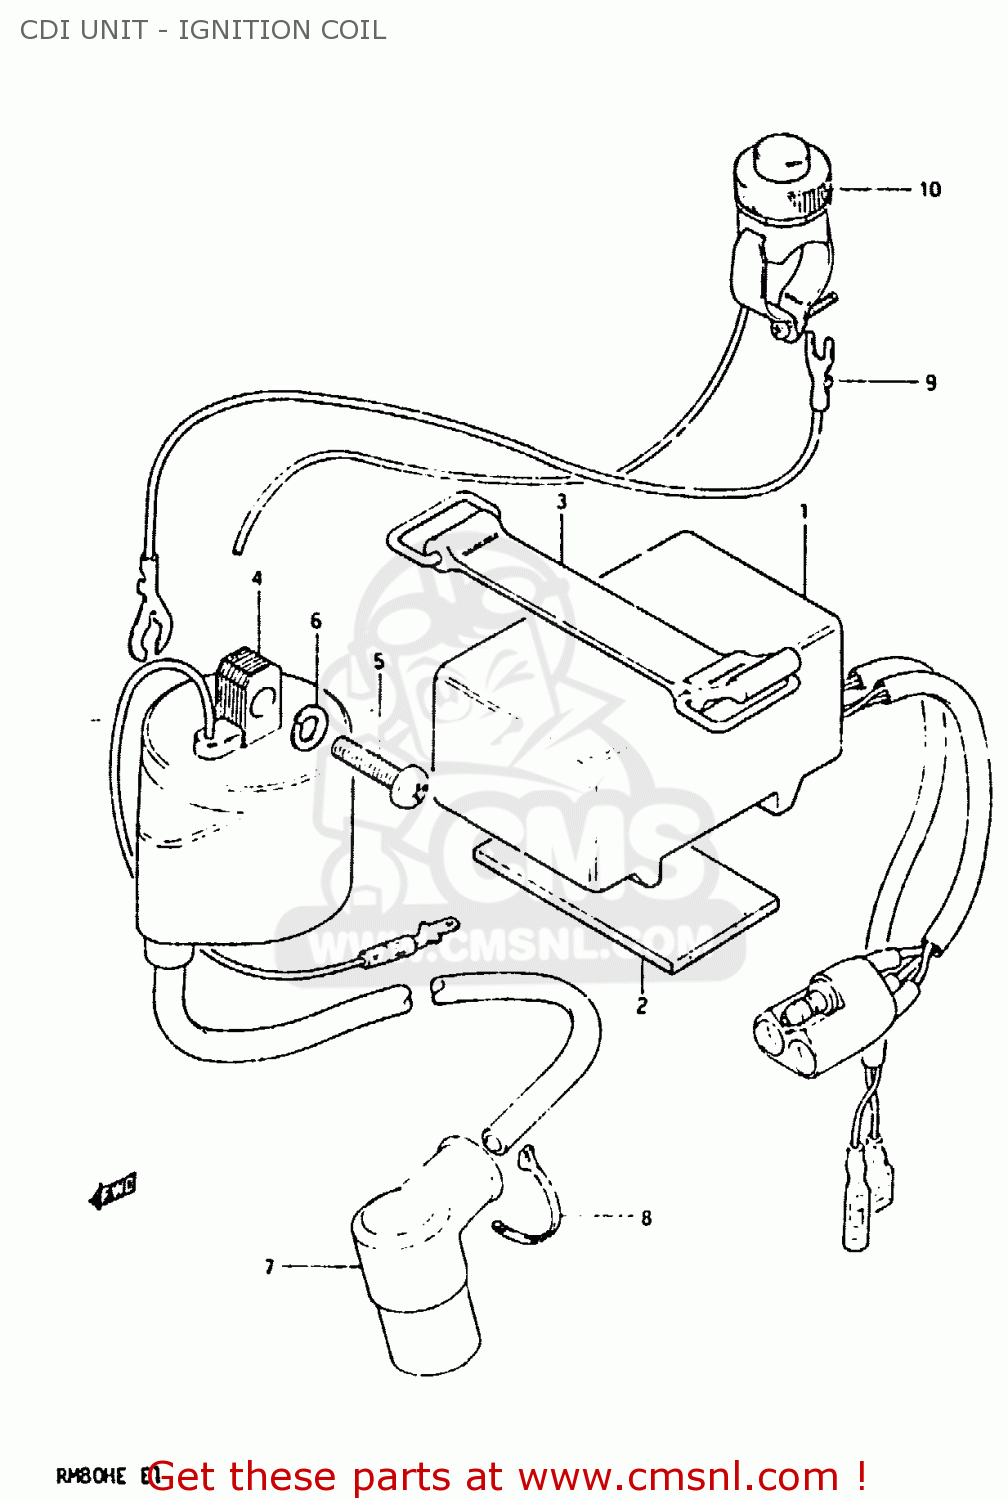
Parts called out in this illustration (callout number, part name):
1	CDI UNIT
2	PROTECTOR,BATTERY
3	BAND
4	COIL ASSEMBLY,IGNITION
5	SCREW
6	LOCK WASHER
7	CAP,SPARK PLUG
8	CLAMP
9	WIRE,ENGINE STOP EARTH
10	SWITCH ASSEMBLY
